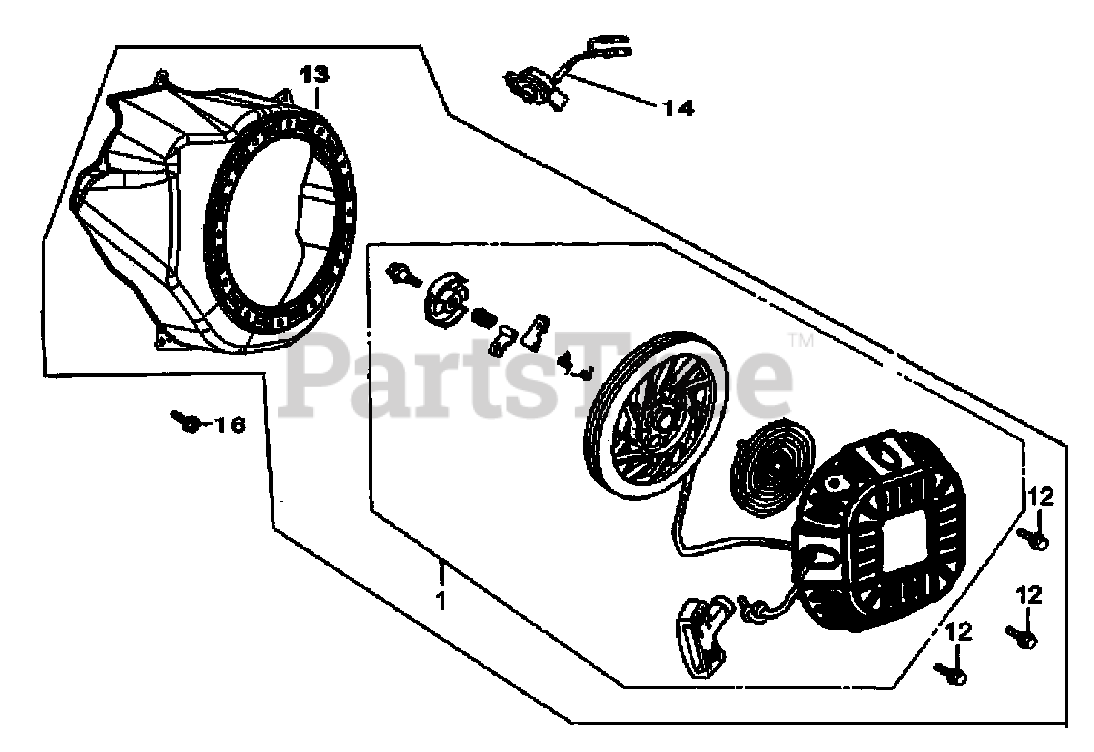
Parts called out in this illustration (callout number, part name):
1	STARTER ASSY.
12	BOLT, FLANGE
13	COVER COMP., FAN
14	SWITCH ASSY., ENGINE STOP
16	BOLT, FLANGE
